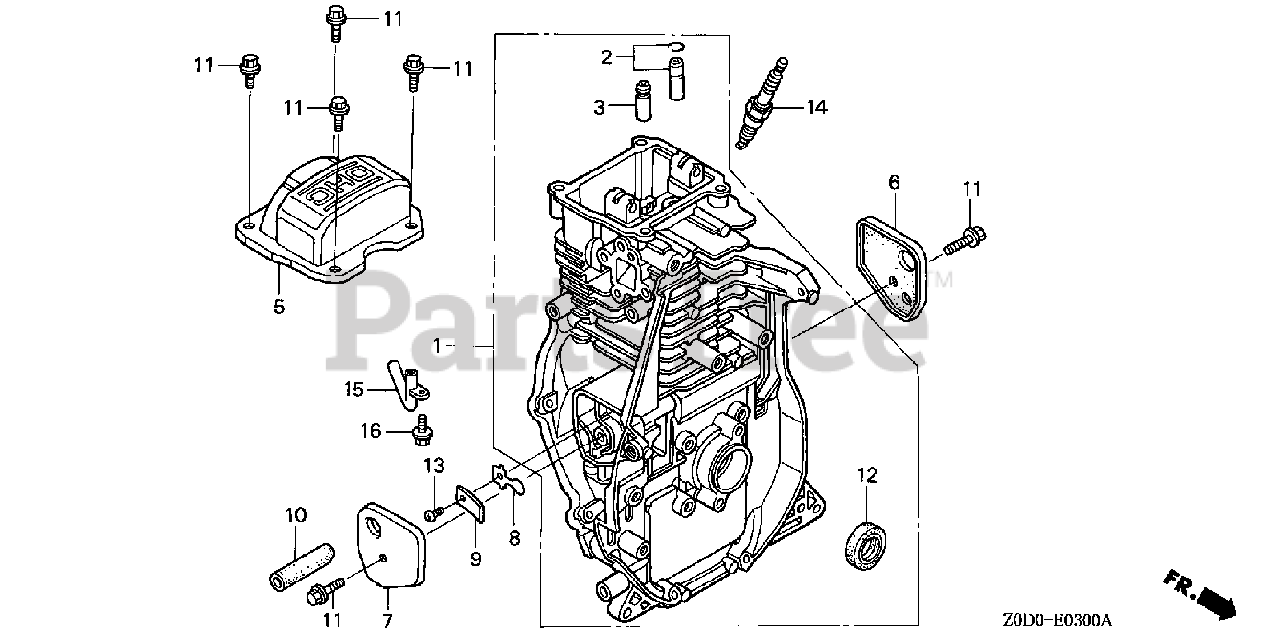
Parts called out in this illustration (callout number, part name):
1	CYLINDER ASSY.
2	GUIDE ASSY., EX. VALVE (OS)
3	GUIDE, VALVE (OS)
5	COVER, HEAD
6	COVER A, BREATHER
7	COVER B, BREATHER
8	VALVE, OIL OUTLET
9	PLATE, STOPPER
10	TUBE, BREATHER
11	BOLT, FLANGE (6X14)
12	OIL SEAL (20X32X6)
13	SCREW, PAN (3X5)
14	SPARK PLUG (U16FSR-UB) (DENSO)
14	SPARK PLUG (CR5HSB)
